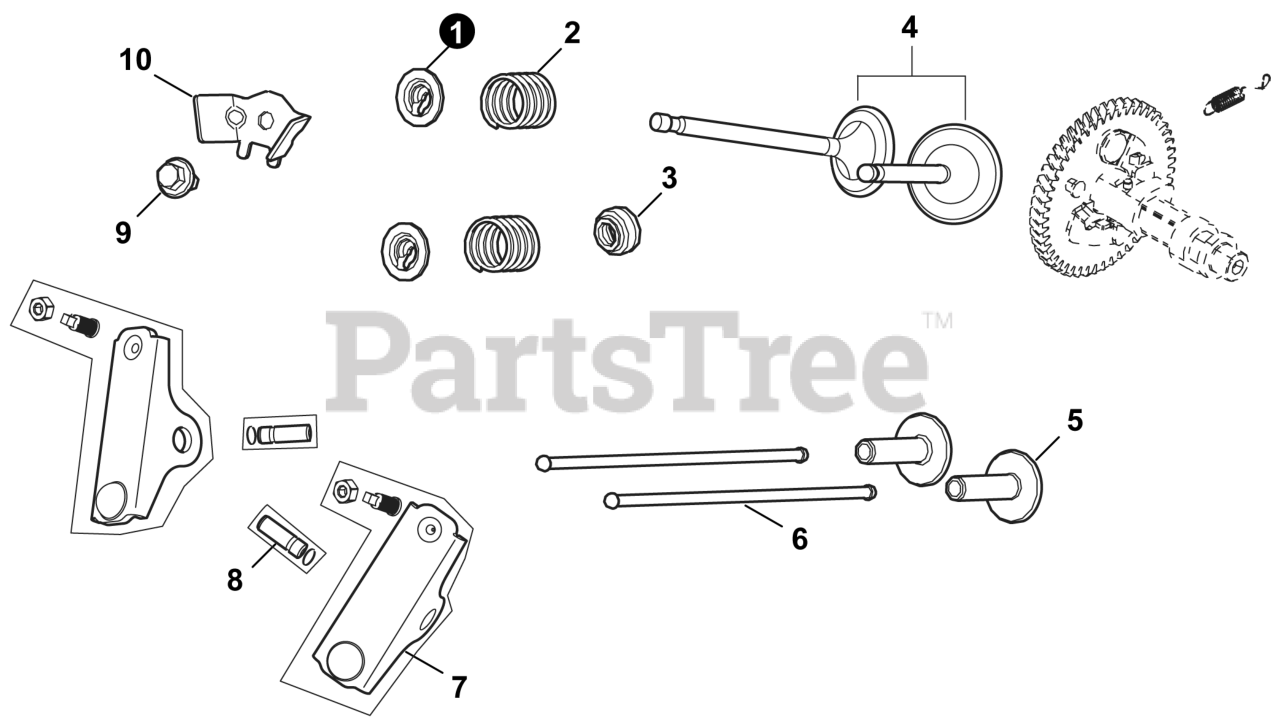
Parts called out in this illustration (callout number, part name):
1	SEAT, VALVE SPRING
2	SPRING, VALVE
3	GUIDE, SEAL
4	VALVES SET, INTAKE/EXHAUST
5	TAPPET, VALVE
6	ROD, PUSH
7	ARM, ROCKER
8	SHAFT,EXHAUST VALVE ROCKER
10	PLATE, PIN OF CYLINDER HEAD COVER
